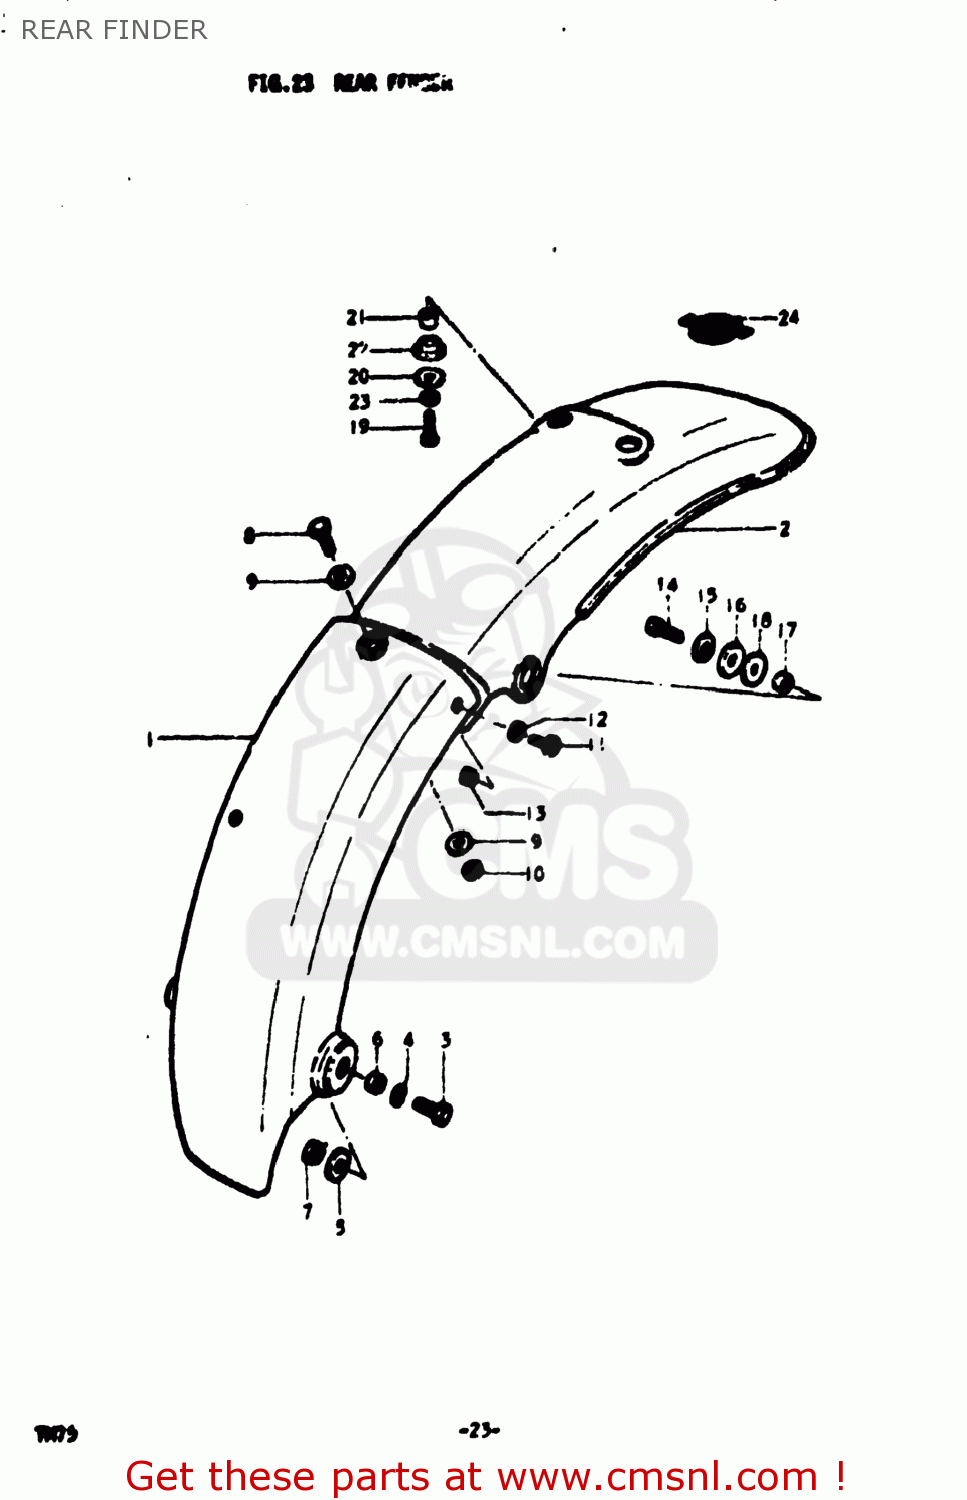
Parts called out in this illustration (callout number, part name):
1	FENDER,REAR
2	FENDER,REAR
3	BOLT
4	WASHER 6MM
5	WASHER (6.5X20X1.2)
6	SPACER
7	NUT
8	BOLT
9	WASHER(6.5X16X1.2)
10	NUT
11	SCREW
12	WASHER 5MM
13	NUT
14	BOLT
15	LOCK WASHER
16	WASHER (6.5X20X1.2)
17	SPACER(6.1X9X7.5)
18	CUSHION
19	BOLT(6X18)
20	WASHER (6.5X20X1.2)
21	SPACER
22	CUSHION
23	LOCK WASHER
